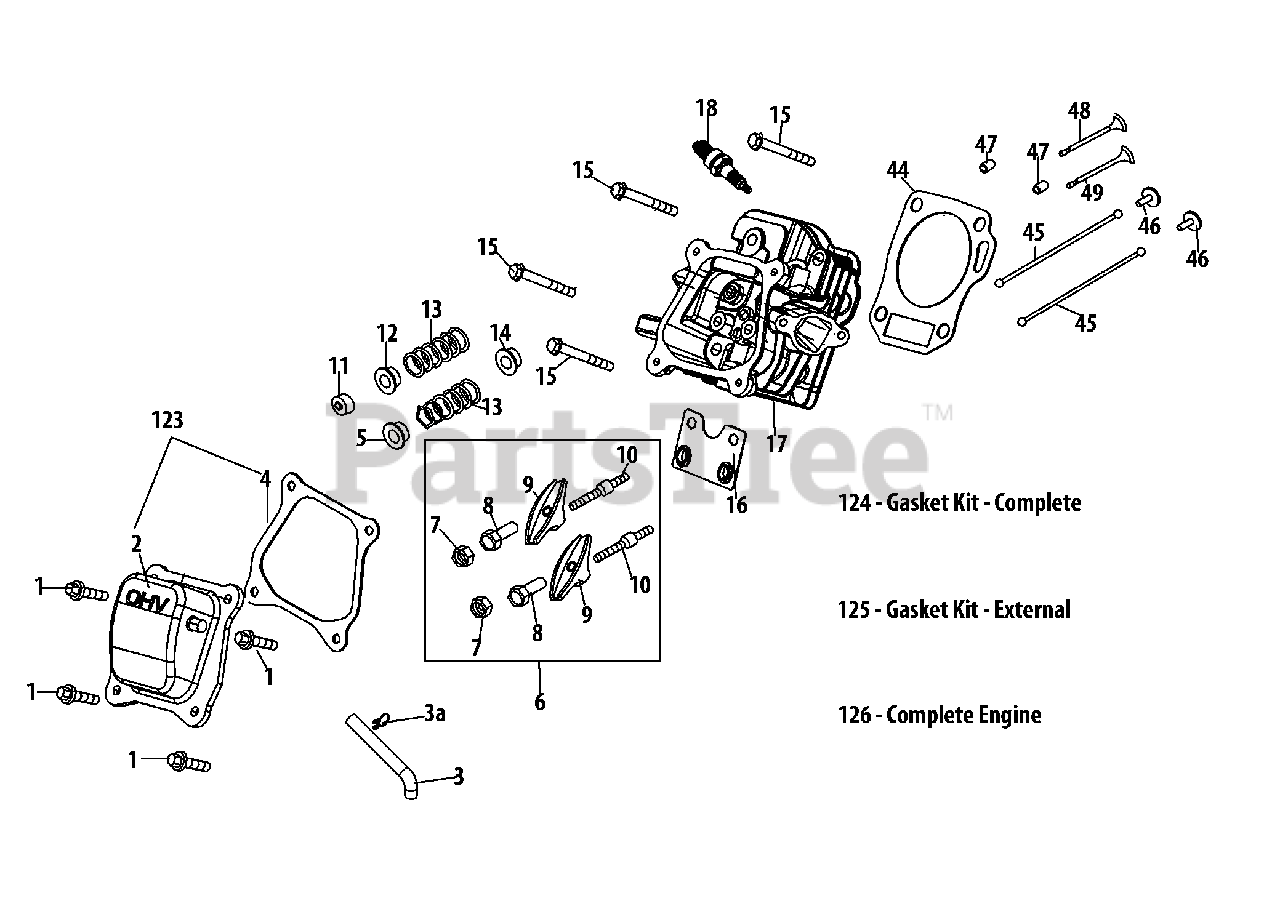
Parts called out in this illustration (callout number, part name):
1	Bolt M6×16
2	Valve Cover
3	Breather Hose
4	Valve Cover Gasket
5	Valve Spring Retainer (Intake)
6	Rocker Arm Assembly
7	Nut, Pivot Locking
8	Adjusting Nut ,Valve
9	Rocker Arm
10	Bolt, Pivot
11	Exhaust Lash Cap
12	Valve Spring Retainer (Exhaust)
13	Valve Spring
14	Valve Seal (Intake)
15	Bolt M8×55
16	Push Rod Guide
17	Cylinder Head Assembly
18	Spark Plug/F6Rtc
44	Gasket, Cylinder Head
45	Push Rod Kit
46	Tappet
47	Dowel Pin 10×16
48	Valve Kit
49	Valve Kit
123	Valve Cover Kit
124	Gasket Kit - Complete
125	Gasket Kit - External
126	Complete Engine
